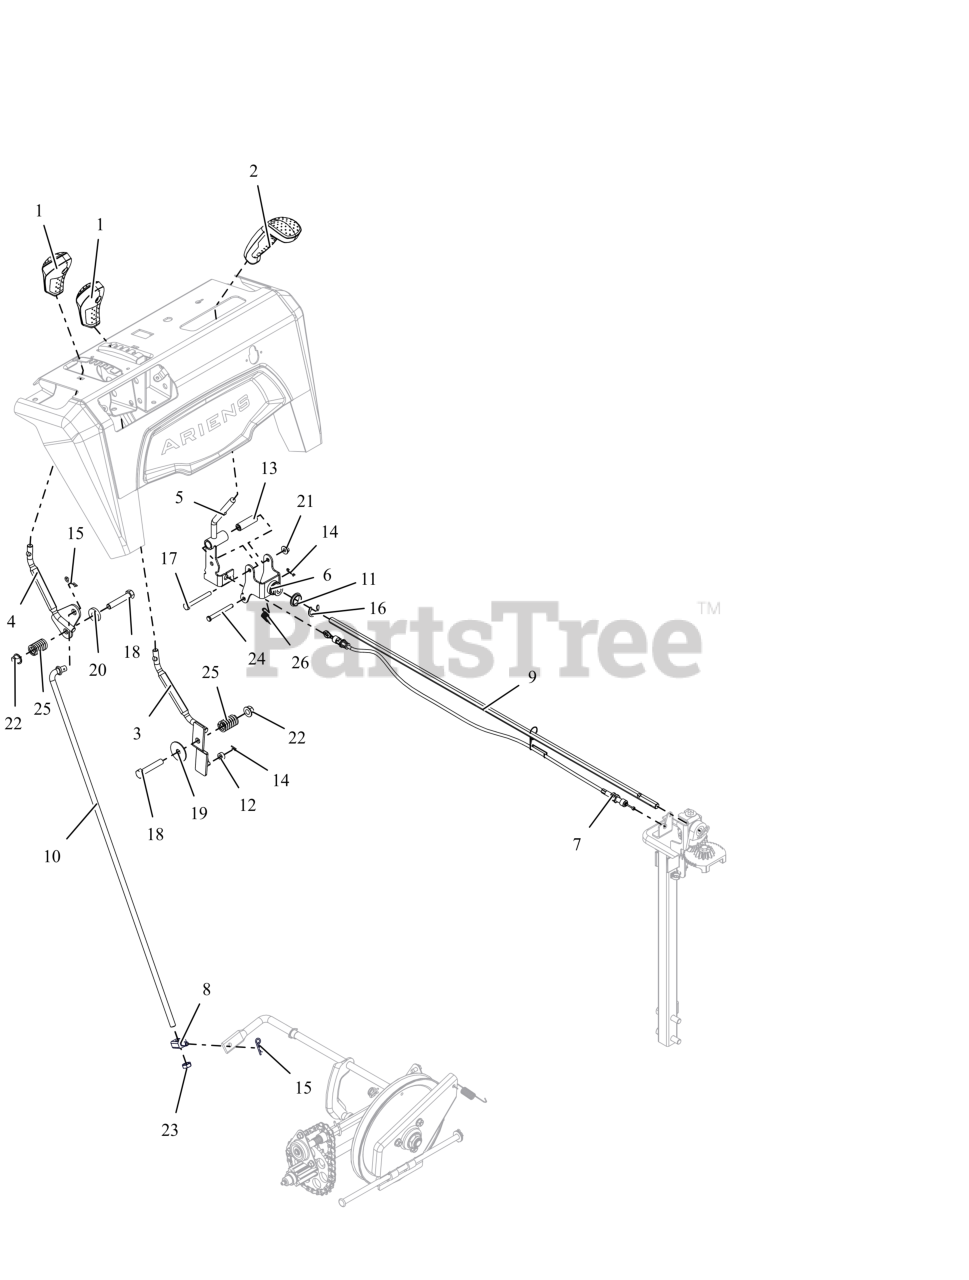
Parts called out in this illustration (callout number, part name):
1	KNOB, CONTROL, DASH
2	HANDLE, QUICK TURN, ASM
3	WELDMENT,LG DASH DEFL CONTROL
4	WELDMENT,LG DASH SPEED CONTROL
5	WELDMENT, CONTROL LEVER
6	WELDMENT, CONTROL BRACKET
7	CABLE, CHUTE LOCK, PRO
8	PIVOT,SHIFT ROD .375-16(TRUNN)
9	ROD, HEX - CHUTE ROTATION
10	ROD, SHIFT - PRO
11	BUSHING, POLYLINER-.75 SNAPIN
12	BSHG-SLV .265X.500X.219
13	BSHG, SLV .265X.505X1.665
14	PIN, HAIR #178 .06X.77 ZCC
15	PIN, HAIR #213 .08X1.19 ZCC
16	E-RING .750X.050
17	BLT,HEX .25-20X2.25 G5 ZCC
18	BLT,HEX .38-16X2.00 G5 ZCC
19	WSHR,FLT .380X1.50X.062 ZCC
20	WSHR, FLT .406X1.00X.188 ZCC
21	NUT-LK-CTR-FLG .25-20 ZC120
22	NUT-LK-TOP-FLG .38-16 ZC120
23	NUT-JAM .375-16 G2 ZCC
24	PIN, CLEVIS - .25 X 2.25 ZCC
25	SG-COMP .125X.781X1.250
26	SPRING-EXT .047X.438X1.45
